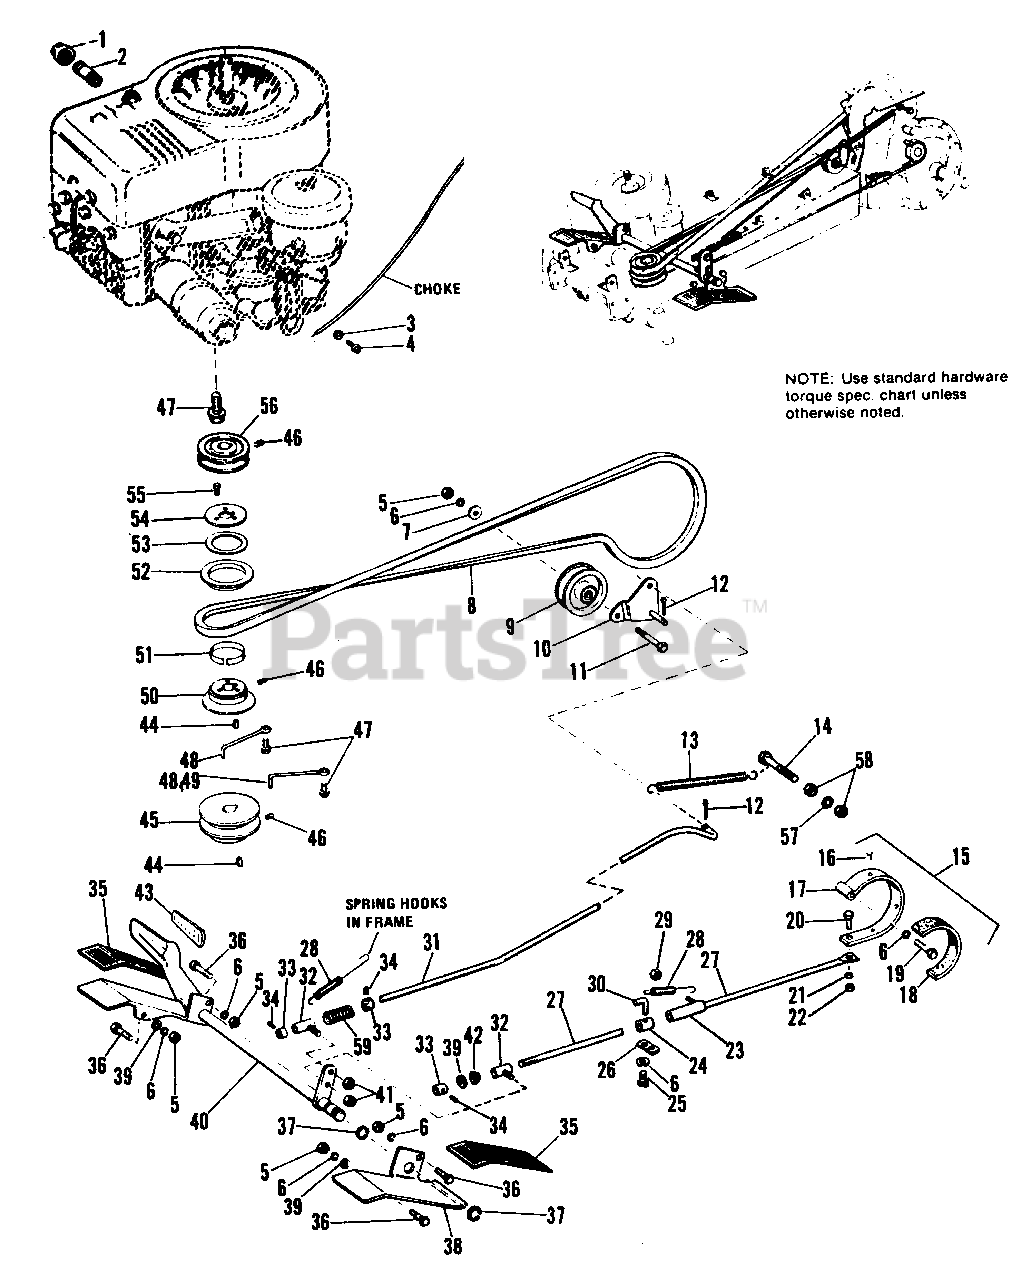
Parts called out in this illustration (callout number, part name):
1	CAP, Pipe, 3/8
2	NIPPLE, Pipe
3	WASHER, Plain, #10
4	SCREW, Machine, #10-32 x 3/8
5	NUT, Hex, Full, 3/8-16 (Qty. 5 on 990489 Only)
6	LOCKWASHER, 3/8 (Qty. 6 on 990489 Only)
7	WASHER, Plain, 5/16
9	PULLEY, Idler
10	BRACKET ASSY.
11	CAPSCREW, Hex Hd., 3/8-16 x 1-1/4
12	PIN, Cotter, 1/8 x 3/4
13	SPRING, Return
14	CAPSCREW, Hex Hd., 5/16-18 x 2-1/2 (990489 Only)
14	CAPSCREW, Hex Hd., 3/8-16 x 1-3/4
15	BRAND ASSY., Brake
16	RIVET, #7 x 1/4
17	BAND, Brake
18	LINING, Brake
19	CAPSCREW, Hex Hd., 3/8-16 x 1-1/2
20	CAPSCREW, Hex Hd., 1/4-20 x 1/2
21	LOCKWASHER, 1/4
22	NUT, Hex, Full, 1/4-20
23	GUIDE ASSY., Rod
24	COLLAR, Parking Brake
25	SCREW, Hex, Taptite, 3/8-16 x 1/2
26	ANCHOR, Spring (990577 Only)
27	ROD, Brake
28	SPRING (Qty. 1 on 990577 Only)
29	LOCKNUT Hex, 1/4-20
30	LOCK, Parking Brake
31	ROD, Clutch (990489 Only)
31	ROD, Clutch
32	GUIDE ASSY., Rod;
33	COLLAR, Set
34	SETSCREW, 1/4-20 x 3/8
35	COVER, Footrest
36	CAPSCREW, Hex Hd., 3/8-16 x 3/4
37	RING, Snap
38	FOOTREST, L.H.
39	WASHER, Plain, 3/8 (Qty. 1 on 990577 Only)
40	SHAFT ASSY., Clutch
41	LOCKNUT, Hex, 5/16-18
42	SPRING (990577 Only)
43	PAD, Pedal
45	PULLEY, Engine
46	SETSCREW, 5/16-18 x 5/16 (Qty. 2 on 990577 Only)
47	SCREW, Hex, Washer Hd., Taptite, 3/8-16 x 1-1/4
48	STOP, Belt (Qty. 1 on 990577 Only)
49	STOP, Belt (990577 Only)
50	PULLEY, Half (990489 Only)
51	BEARING (990489 Only)
52	PULLEY, Half (990489 Only)
53	WASHER, Thrust (990489 Only)
54	WASHER, Thrust (990489 Only)
55	SCREW, Hex Self Tapping 1/4-20 x 1/2 (990489 Only)
56	PULLEY, Engine (990489 Only)
57	LOCKWASHER, 5/16 (990489 Only)
58	NUT, Hex, Full, 5/16-18 (990489 Only)
59	SPRING (990577 Only)
